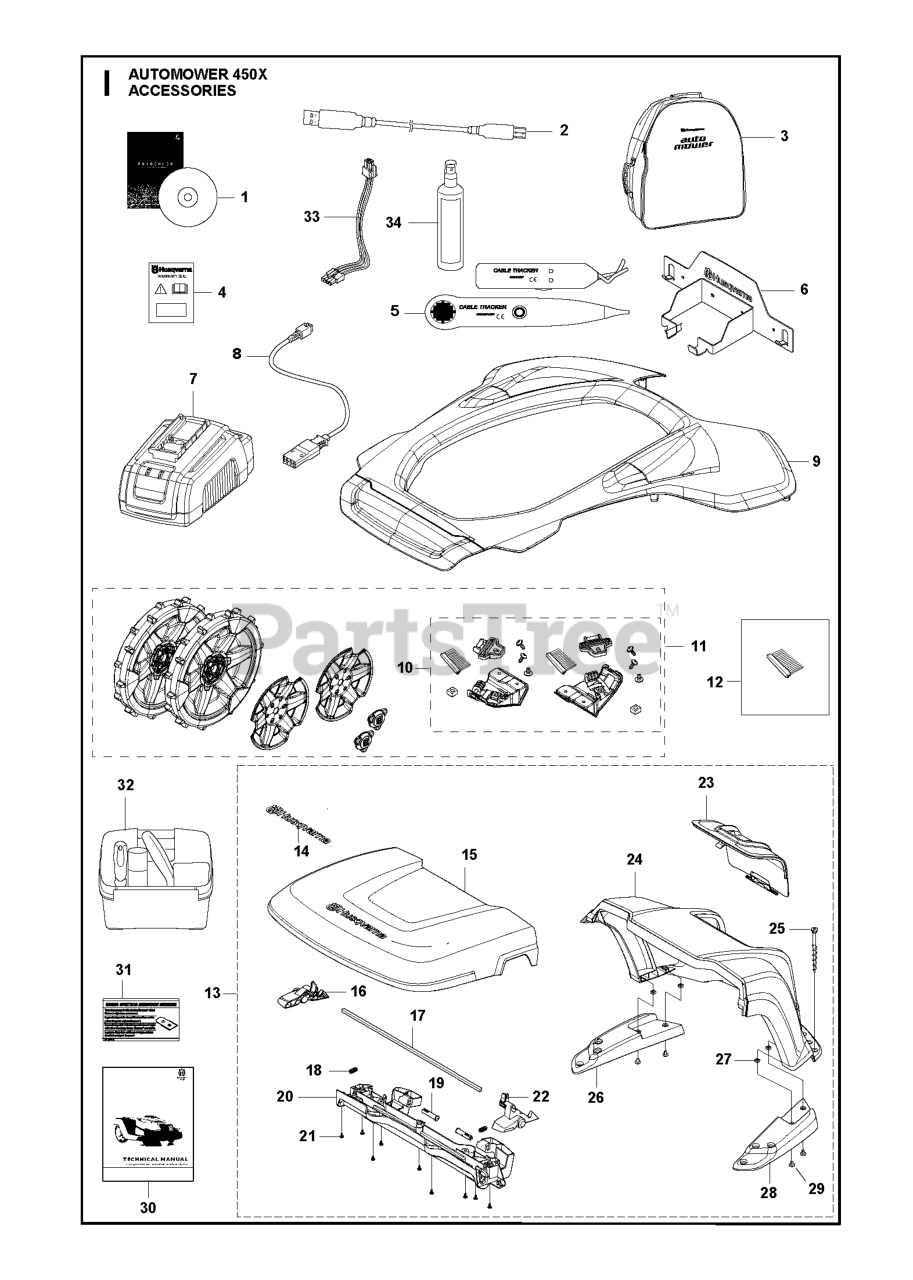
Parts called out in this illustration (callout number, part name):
1	DVD AUTOCHECK EXP SERVICE
2	CABLE WHITE ALT GREY
3	BAG
4	LABEL WARRANTY SEAL DEALER
5	TEST EQUIPMENT
6	MISC. BLISTER WALL HANGER
7	CHARGER BATTERY TEST
8	CABLE ASSY QUICK CHARGER
9	TOP COVER WHITE/ 450
9	TOP COVER ORANGE/ 450
9	BODY KIT
10	BRUSH KIT 430/450
11	REAR WHEEL KIT W/ BRUSHES
12	WHEEL BRUSH REFILL KIT
13	430/450 HOUSE KIT
14	DECAL.HUSQVARNA.210MM
15	KIT LID - AUTOMOWER HOUSE
16	HANDLE RELEASE LEFT
17	ROD
18	SPRING SPRING CAP
19	HINGE PIN
20	BEAM
21	SCREW 14MM
22	HANDLE RELEASE RIGHT
23	HATCH
24	COVER BASE P2 HOUSE
25	SCREW KIT CS
26	SUPPORT BASE LEFT
27	NUT
28	SUPPORT BASE RIGHT
29	SCREW IHPANM M6X25 4.6 ZP-BC
31	DECAL WARNING ORIGINAL BLADE E
31	ORIGINAL PARTS STICKER
32	CLEANING AND MAITENANCE KIT AM
32	WIRING ASSY BATTERY CABLE
34	AUTOMOWER ACCY
